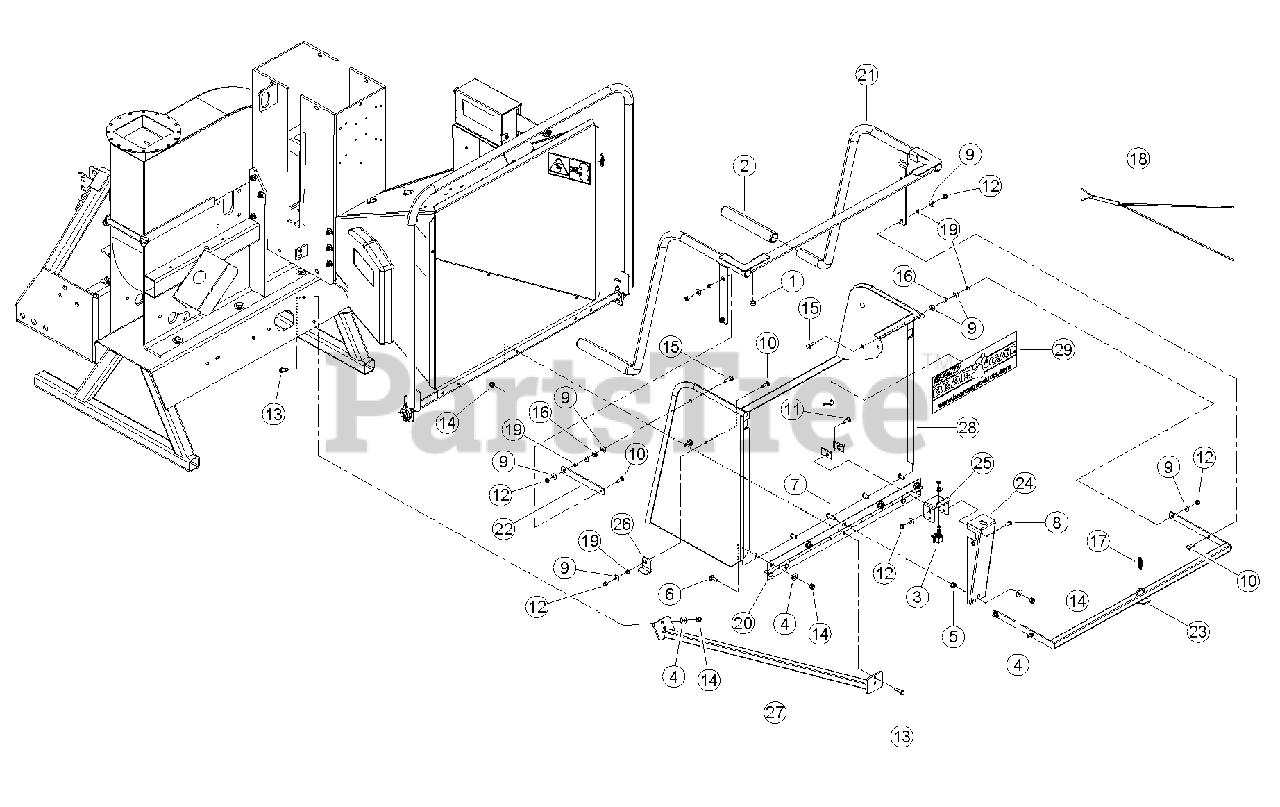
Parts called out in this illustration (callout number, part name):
1	BUMPER, RUBBER
2	GRIP, 1.219 X 10.00
3	SWITCH, N/C MOMENTARY PLUNGER
3	SWITCH, MOMENTARY IP67
4	WASHER, 3/8 FLAT ZP
5	NUT, 3/8 SERRATED FLANGE NC ZP
6	BOLT, 3/8 X 1 CRG GR5 NC ZP
7	BOLT, 3/8 X 1-1/2 CRG GR5 NC ZP
8	SCREW, 11/32 X 7/8 HWH AB THREAD ZP
9	WASHER, 5/16 FLAT ZP
10	BOLT, 5/16 X 1 CRG GR5 ZP
11	BOLT,5/16 X 7/8 CRG GR5 NC ZP
12	NUT, 5/16 NE NYLOCK ZP
13	BOLT, 3/8 X 1-1/4 HEX HD GR5 ZP
14	NUT, 3/8 NE NYLOCK ZP
15	BOLT, 5/16 X 1-1/4 CRG GR5 ZP
16	WASHER, 5/16 ID 7/8 OD NYLON FLAT
17	SPRING, 1/2 X 2.00 LONG ZP
18	HARNESS, SAFETY BAR
19	SPACER, IDLER PIVOT
20	HINGE, EXTENSION TRAY
21	WELDMENT, KNEEBAR
22	LINK, PARALLEL
23	WELDMENT, KNEEBAR PIVOT
24	SHIELD, KNEEBAR SWITCH
25	BRACKET, SWITCH
26	LOCK, SAFETY BAR
27	WELDMENT, CHUTE SUPPORT
28	ASSEMBLY, EXTENSION TRAY SERVICE PART
29	DECAL, BEARCAT WEB
